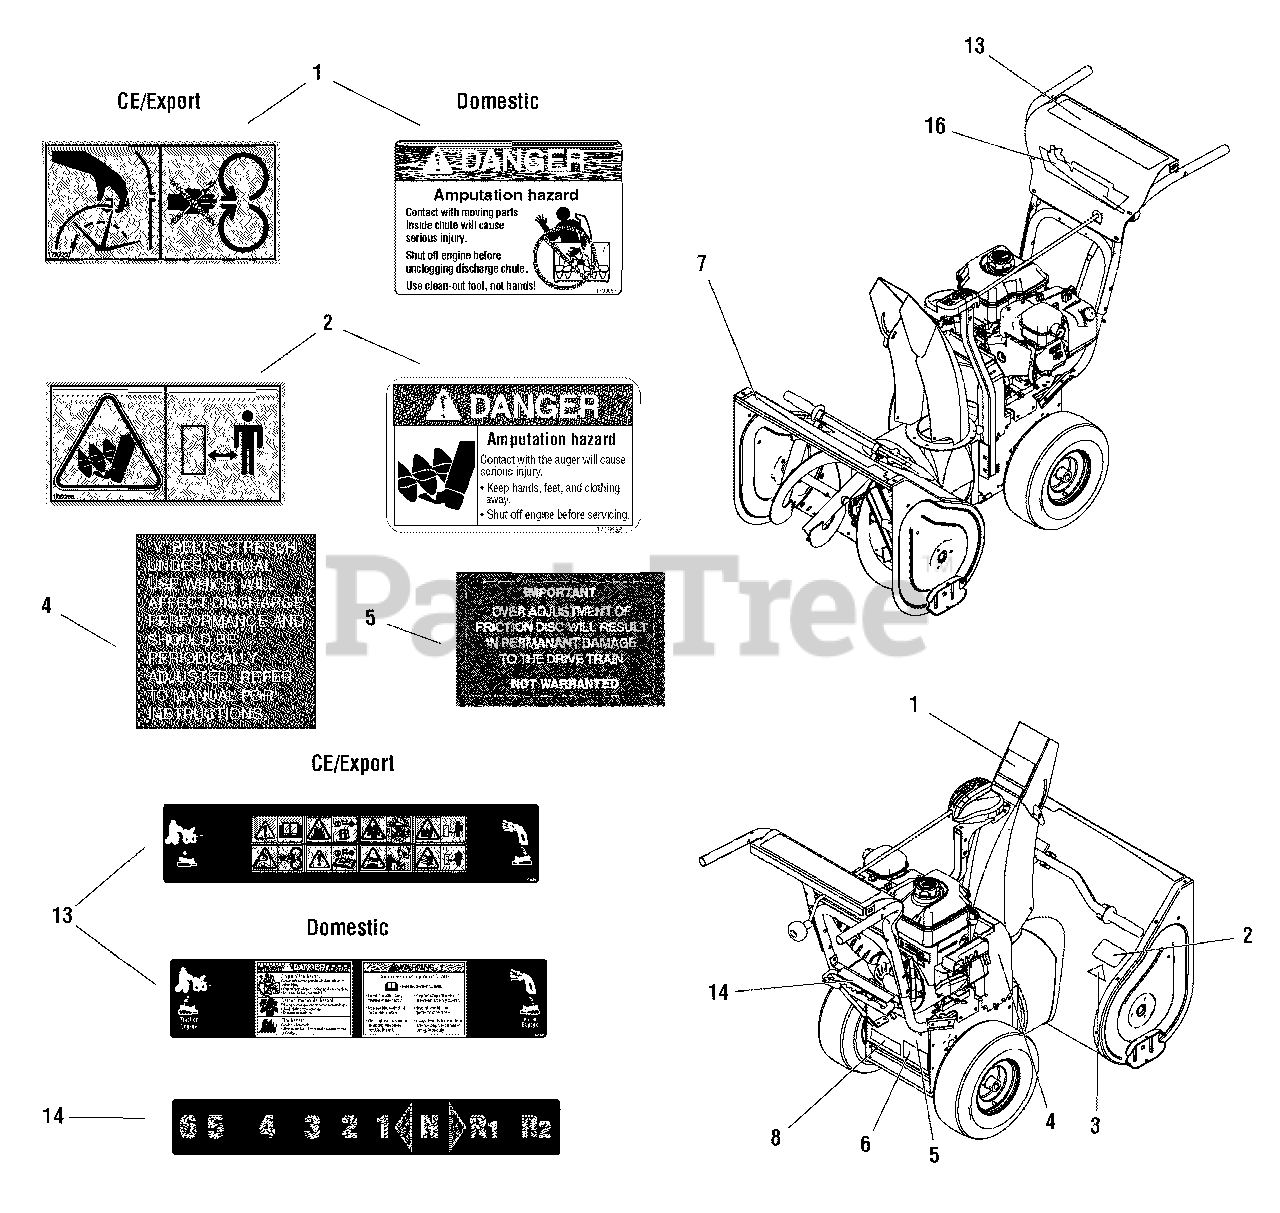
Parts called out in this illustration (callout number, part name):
1	DECAL, Chute Warning
1	DECAL, Danger Amputation Hazard
2	DECAL, Impeller Warning
2	DECAL, Danger Avoid Injury, Auger
3	*DECAL, OPEI
4	DECAL, Belt Stretch and Adjustment
5	DECAL, Over Adjust of Friction Disc
6	*STICKER, Serial w/Bar Code
7	DECAL, SMI Stripe 924IE
7	DECAL, SMI Stripe 924IR
7	DECAL, SMI Stripe 924I
8	DECAL, Touch Up Paint
13	DECAL, Dash
14	DECAL, Speed Control
16	DECAL, SMI Dash Swoosh
